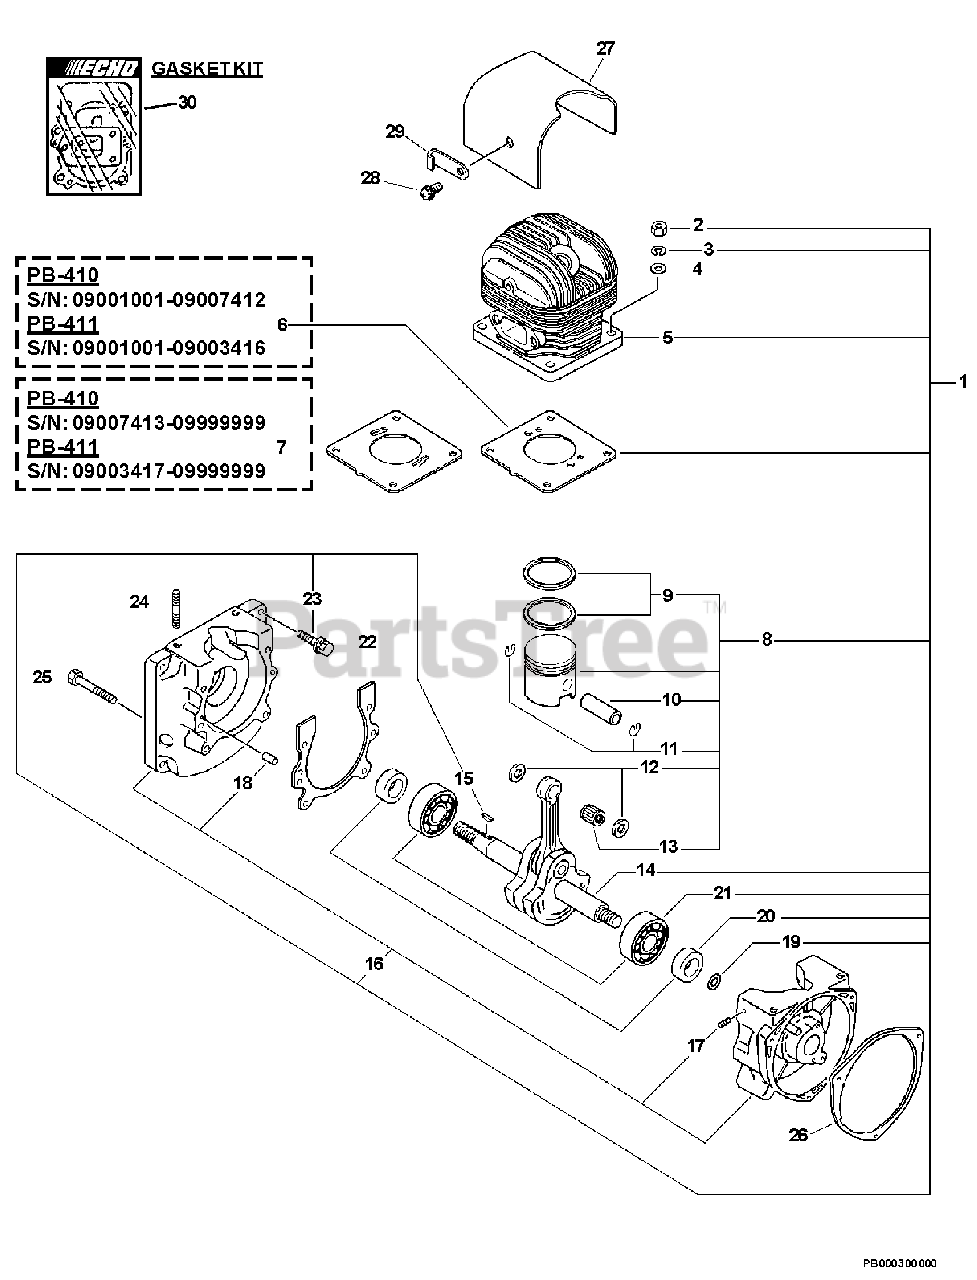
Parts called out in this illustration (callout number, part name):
1	SHORT BLOCK -- SB1084
2	LOCKNUT - 6
3	LOCKWASHER - 6
4	WASHER - 6
5	CYLINDER
6	GASKET, CYLINDER
7	GASKET, CYLINDER
8	PISTON KIT
9	RING, PISTON
10	PIN, PISTON
11	RING, RETAINING - 8
12	SPACER, PISTON
13	BEARING, NEEDLE
14	CRANKSHAFT ASSY
16	CRANKCASE KIT
17	CONNECTOR
18	PIN - LOCATING
19	WASHER - 10
20	SEAL, OIL
21	BEARING, BALL - 6202
22	GASKET, CRANKCASE
23	BOLT - 6X25
26	GASKET, STARTER
27	SHIELD, CYLINDER
28	BOLT - 6X10
30	GASKET KIT
